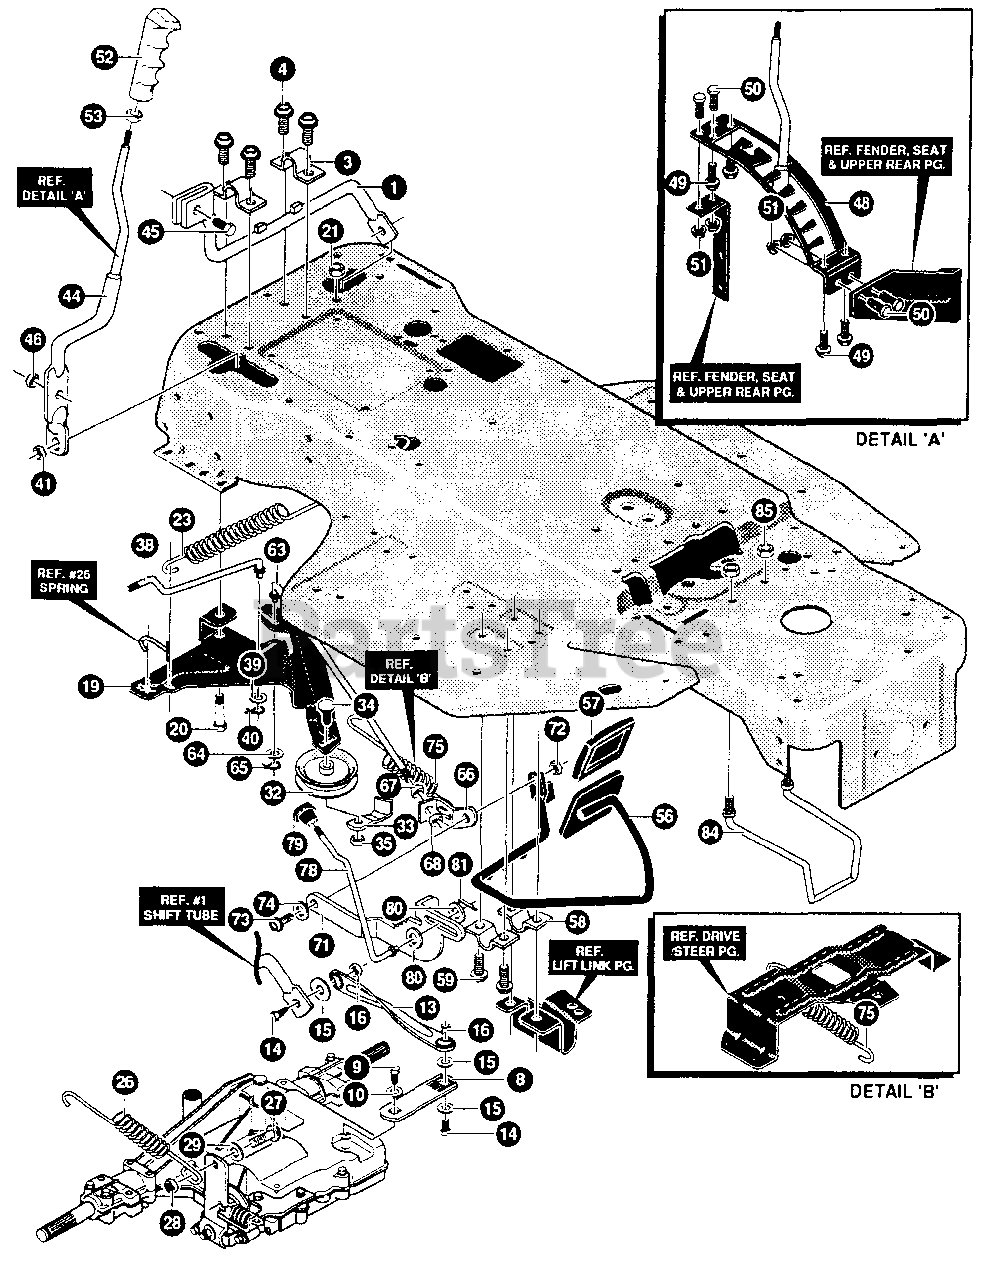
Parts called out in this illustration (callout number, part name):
1	TUBE ASSY, SHIFT BLACK 173
3	CLIP, SHIFT LEVER
4	SCREW, 5/16-18X .50 WAHHTAP
8	LEVER,TRANS SHIFT
9	SCREW, 1/4-28X .75 NYLHHC
10	WASHER, .750X.250 SP-TRANSAXLE
13	LINK,TIE ROD SHIFT 7 812C/L
14	SCREW, 3/8-16X1.25
15	WASHER, FLAT .406X .81X.065
16	NUT, 3/8-16 REGHXCTRLK
19	ARM IDLER
20	BOLT,.500X1.280 HHSH 3/8-16
21	NUT, 3/8-16 REGHXCTRLK
23	SPRING, CLUTCH
26	SPRING, BRAKE 1.00ODX3.12X.120
27	BOLT, .500X .375 HHSH 5/16-18
28	NUT, 5/16-18 REGHEXCTRLK
29	WASHER, FLAT .515X1.31X.09
32	PULLEY. IDLER BFF
33	BELT RETAINER
34	BOLT, 3/8-16X2.00 CARRSN
35	NUT, 3/8-16 HWDFL WHIZ-LOCK ZN
38	ROD, SHIFT-ON-THE-GO
39	WASHER, FLAT .406X .81X.065
40	PIN, HAIR.072 DIAX1.13LG
41	NUT, 3/8-16 HEXNYL
44	TUBE ASSY, SHIFT PIVOT
45	BOLT .375X.4001/4-20X.47
46	NUT, 1/4-20 REGHEXCTRLK
48	QUADRANT, SHIFT P930-6SP ERO
49	SCREW, 1110 X .50 HHTAPPST
50	SCREW, 1/4-20X .75
51	NUT, 1/4-20 WDFLWHIZ-LK
52	HANDLE, 3/8-16 MOLDED
53	NUT, 3/8-16 REGHX
56	WELD ASSY CL/BR ARM
57	PAD,CLUTCH/BRAKE MOLD W/L
58	BRACKET CL/BR ARM
59	SCREW, 5/16-18X .50 WAHHTAP
63	ROD, CLUTCH
64	WASHER, FLAT .281X .63X.065
65	PIN, COTTER .062 DIAX.75LG
66	BRACKET, BRAKE ROD
67	NUT, 5/16-18 HEXKEPS
68	NUT, 5/16-18 REGHEXCTRLK
71	LEVER, PARK BRAKE
72	NUT, 5/ 16-18 REGHEXCTRLK
73	BOLT, .500X .375 HHSH 5/16-18
74	WASHER, WAVE .50 ID
75	SPRING .071 X .62 X 4 37
78	ROD, PARKING BRAKE
79	KNOB, PARK BRAKE BLK853
80	WASHER, FLAT .250X .56X.049
81	PIN, COTTER .062 DIAX.75LG
84	GUIDE, BELT 820 TRANSAXLE
85	NUT, 5/16-18 REGHEXCTRLK
